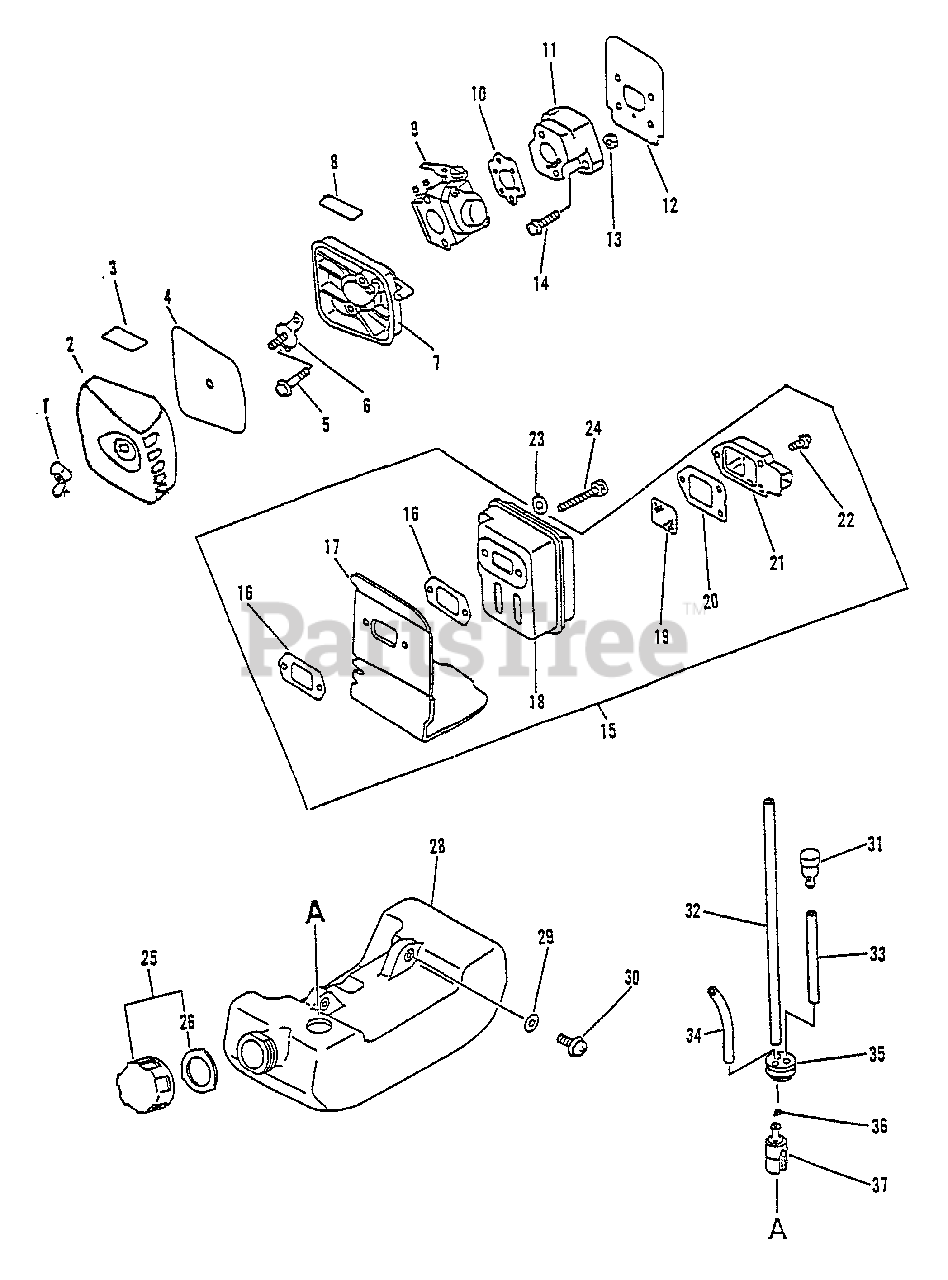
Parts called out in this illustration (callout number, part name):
1	WINGNUT - 6
2	COVER, AIR FILTER
3	LABEL - TOP
4	FILTER, AIR
5	SCREW 5×64
6	PLATE, PREVENT
7	CASE, AIR FILTER
8	LABEL, CHOKE
9	CARBURETOR - C1U-K29
10	GASKET, INTAKE
11	INSULATOR, INTAKE
12	HEAT SHIELD, INTAKE
13	NUT M5
14	SCREW 5×20
15	MUFFLER ASSY
16	GASKET, EXHAUST
17	COVER, EXHAUST
19	SCREEN, SPARK ARRESTER
20	GASKET, EXHAUST
21	GUIDE, EXHAUST - INNER
22	SCREW 4×10
23	WASHER, FLAT 5.5×10×0.8
24	BOLT 5×55
25	CAP ASSY
26	GASKET, FUEL CAP
28	TANK, FUEL
29	WASHER 5.5×12×0.8
30	SCREW 5×16
31	VENT ASSY
32	PIPE, FUEL 3x-5x-180
33	PIPE, FUEL 3x-5x-70 BLACK
34	PIPE, FUEL 3×6×80 CLEAR
35	GROMMET, FUEL
36	CLIP 6 MM
37	FILTER, FUEL
